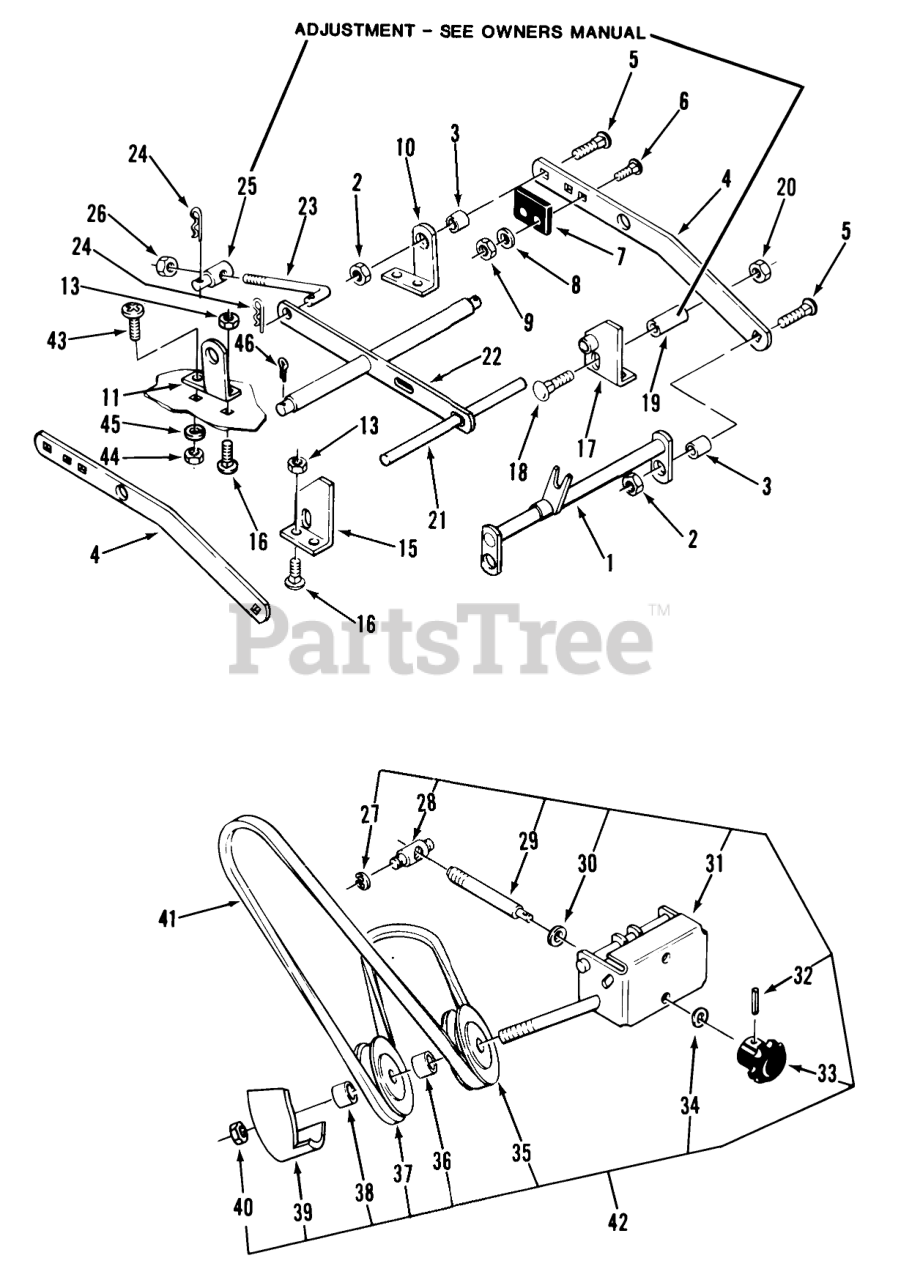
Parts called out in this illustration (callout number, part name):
1	Hitch
2	LOCKNUT-FLANGE
3	SPACER
4	Bar Draft
5	Bolt
6	Bolt-Carriage
7	BUMPER
8	Collar
9	Nut
10	LH Rear Bracket
11	Rear Bracket RH
13	Nut
15	Front Bracket RH
16	Bolt-Carriage
17	Front Bracket LH
18	CARRIAGE BOLT -4
20	Nut
21	Front Shaft
22	Leveler
23	ROD-LEVEL ADJUST
24	Hairpin
25	TRUNNION-LIFT
26	NUT
27	RING-RETAINING
28	TRUNNION-DOUBLE
29	ROD ADJ
30	Washer
31	Front Support
32	PIN-ROLL
33	KNOB-ADJUSTMENT
34	WASHER-SPRING
35	Pulley-V
36	SPACER
37	PULLEY-FLAT IDLER
38	SPACER-OUTER
39	Belt Cover
40	Nut
41	V-BELT
42	ASM-SUPPORT,IDLER
43	PAN HEAD SCREW-4
44	Nut
45	LOCKWASHER
46	Cotter Pin
